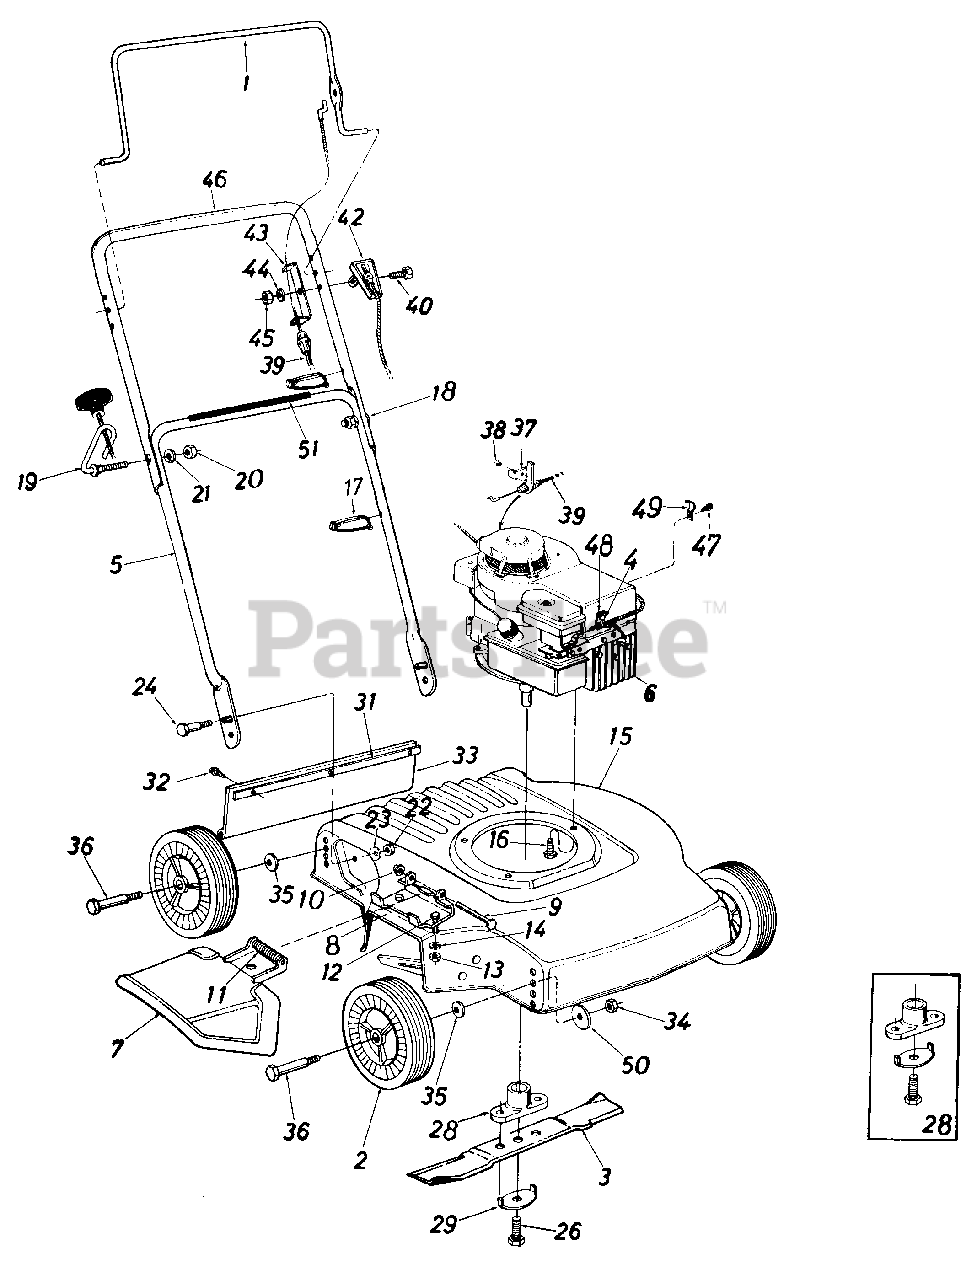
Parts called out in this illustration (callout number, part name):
1	Control Handle-L.H.
3	18" Blade
4	Hex Wash. Hd. AB-Tap Scr. #8 x .50" Lg.
5	Lower Handle (Painted)
6	Engine
7	Chute Deflector Ass'y. Comp.
8	Adapter Plate
9	i Pivot Pin
10	Push Nut 1/4" Rod
11	Torsion Spring
12	Hex Bolt 1/4-20 x .50" Lg.
13	Hex Nut 1/4-20 Thd.
14	L-Wash. 1/4" I.D.
15	18" Deck Ass'y.
16	Hex Wash. Hd. TT-Tap Scr. 3/8-16 x 1.00" Lg.
17	Cable Tie
18	Curved Carriage Bolt 5/16-18 x 1.38" Lg.
19	Rope Guide Bolt
20	Hex Nut 5/16-18 Thd.
21	L-Wash. 5/16" I.D.
22	Hex Ins. L-Nut 5/16-18 Thd.
23	Bell-Wash. .345" I.D. x .88"
24	Shoulder Bolt .437" Dia. x .180
26	Hex Bolt 3/8-24 x 1.5" Lg. Grade 5
28	Blade Adapter Kit
29	Blade Bell-Washer
31	Retaining Strip
32	Hex Wash. Hd. AB-Tap Scr. 1/4 " x .62" Lg.
33	Rear Flap Ass'y.
34	Hex Nut 3/8-16 Thd.
35	Bell-Wash. .400" I.D. x .88" O.D.
36	Shld. Bolt .498" Dia. x 1.450" Lg .
37	Cable Bracket
38	Pop Rivet .156" Dia. x .379
39	Control Cable-36"
40	Hex Bolt 1/4-28 x 1.75" Lg.
42	Throttle Control Ass'y. Comp.
43	Cable Mounting 8rkt.
44	Spr. Wash. .27" I.D. x .57" O.D.
45	Hex Nut 1/4-28 Thd.
46	Upper Handle (Painted)
47	Hex B-Tap Scr. #10 x .38" Lg.
48	Casing Clamp
49	Casing Clamp
50	Fl-Wash. .398" I.D. x 1.13"
51	Instruction Label-Handle
